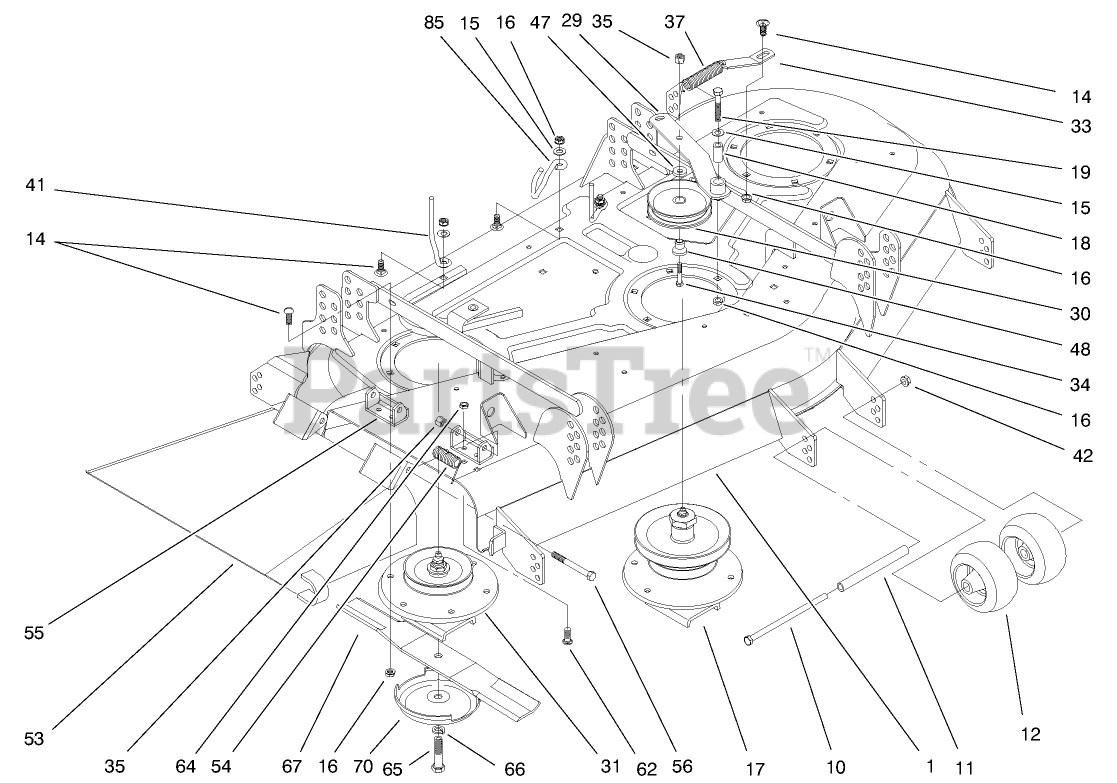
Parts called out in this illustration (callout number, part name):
1	52" DECK W/DECALS
10	SCREW-HH
11	SPACER-WHEEL
12	WHEEL-GAGE
14	SCREW-CARR
15	WASHER-FLAT
16	NUT-HF
17	HOUSING - SPINDLE ASM
18	SLEEVE
19	SCREW-HH
29	IDLER ARM ASM
30	PULLEY-IDLER
31	Spindle Hsg ASM
33	PLATE-SPRING
34	SCREW-HH
35	NUT-HEX
37	SPRING-EXTENSION
41	ROD-BELT
42	NUT-LOCK, NI
47	WASHER-FLAT
48	BUSHING-PULLEY
53	DEFLECTOR
54	SPRING
55	BRACKET-PIVOT
56	SCREW-HH
62	SCREW-CARR
64	NUT-LOCK, CONE
65	SCREW-BLADE
66	WASHER-LOCK
67	Blade
70	CUP-SCALP, ANTI
85	GUIDE-BELT
